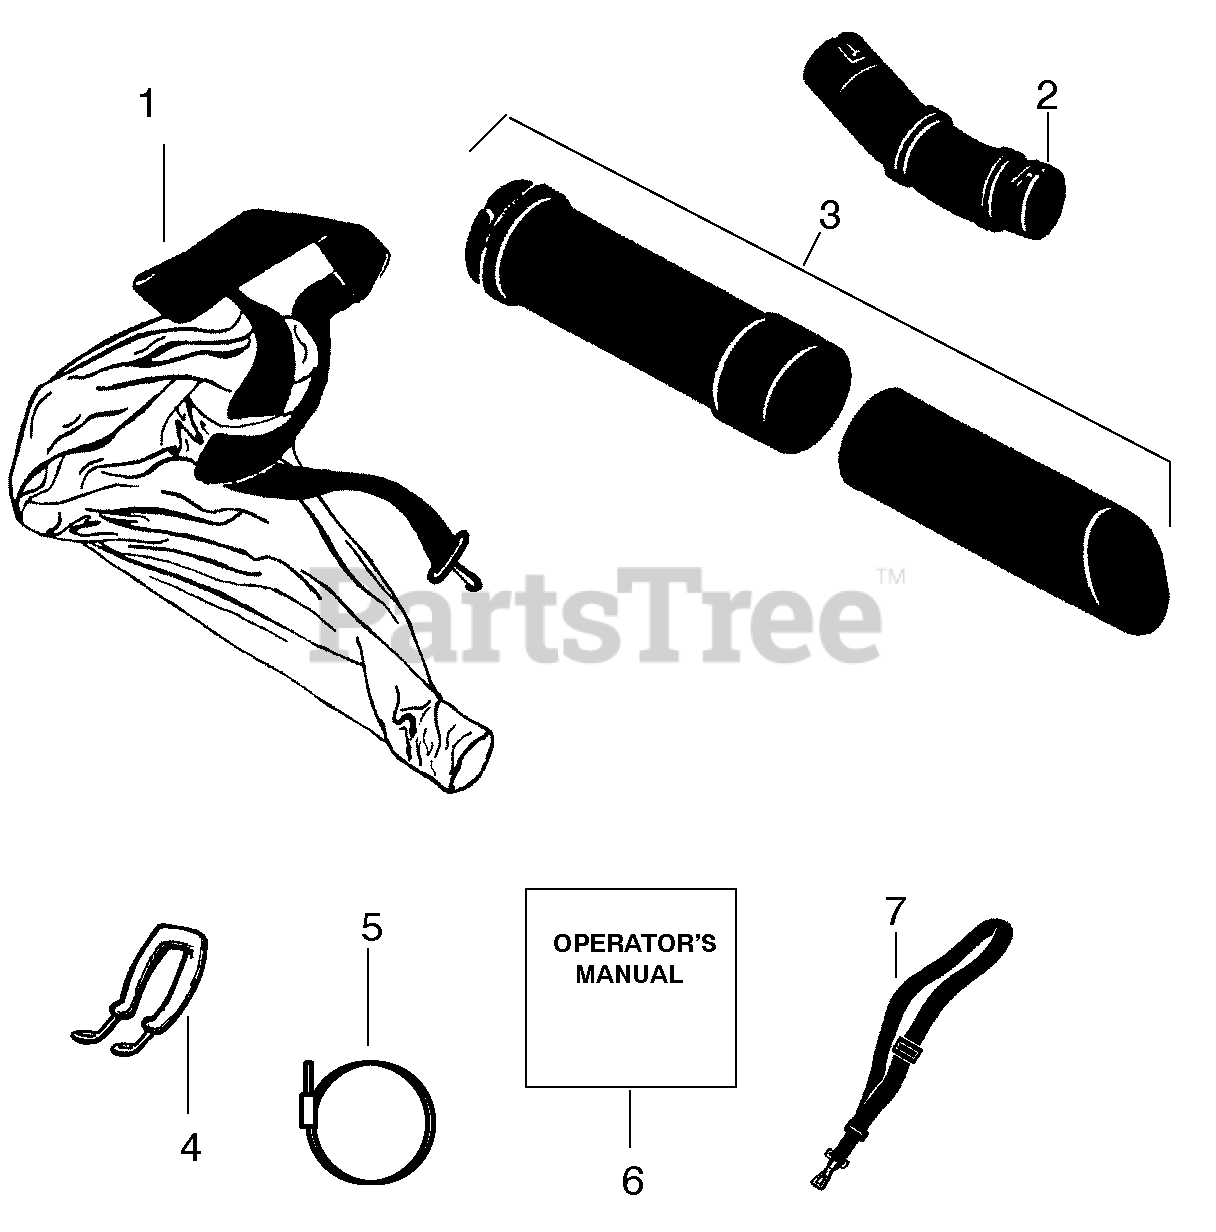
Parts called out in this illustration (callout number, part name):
1	Vac Bag Assy
2	Elbow-Vac Bag
3	Vac Tube Ass'y.
4	Handle-Rear
5	Clamp-Intake Tube
6	Operator Manual
7	Assy.-Shoulder Strap
